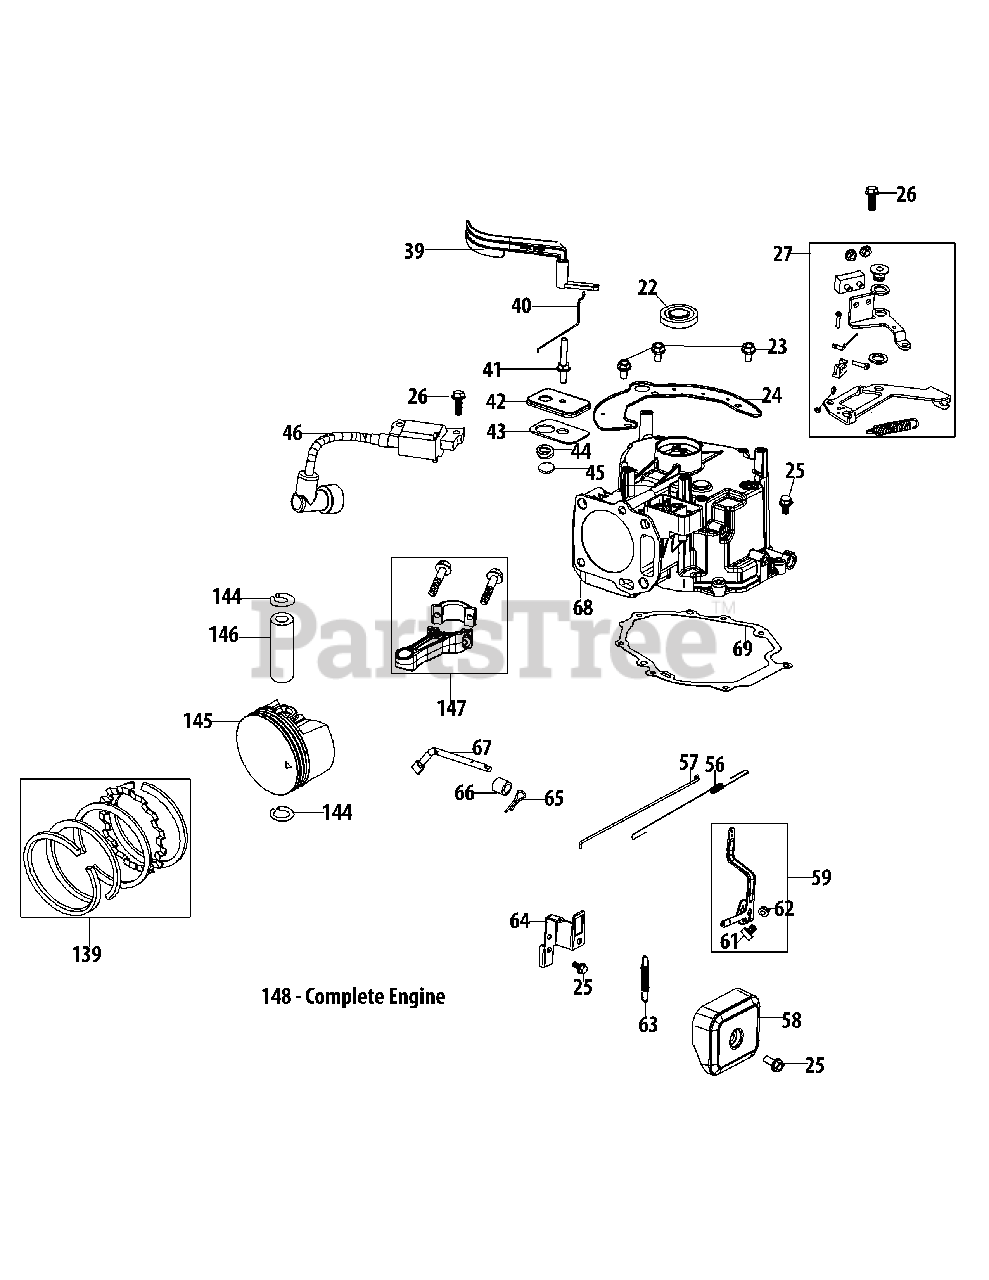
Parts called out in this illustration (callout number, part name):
22	Upper Crankshaft Seal
23	Bolt M6×10 Shroud Cover Plate
24	Shroud Cover Plate
25	Bolt M6×14 Multi-Purpose
26	Bolt M6×25 Ignition Coil/Brake
27	Brake Assembly
39	Air Vane
40	Choke Linkage
41	Air Vane Pivot Stud
42	Breather Cover Plate
43	Breather Gasket
44	Breather Valve Spring
45	Breather Valve
46	Ignition Coil Assembly
56	Throttle Linkage Spring
57	Throttle Linkage
58	Governor Shield
59	Governor Arm Assembly
61	Governor Arm Bolt
62	Governor Arm Nut M6
63	Governor Spring
64	Component Bracket
65	Governor Arm Shaft Cotter Pin
66	Governor Seal
67	Governor Arm Shaft
68	Crankcase
68	Short Block
69	Crankcase Cover Gasket
139	Piston Ring Set
144	Piston Pin Snap Ring
145	Piston
146	Piston Pin
147	Connecting Rod Assembly
148	Complete Engine
